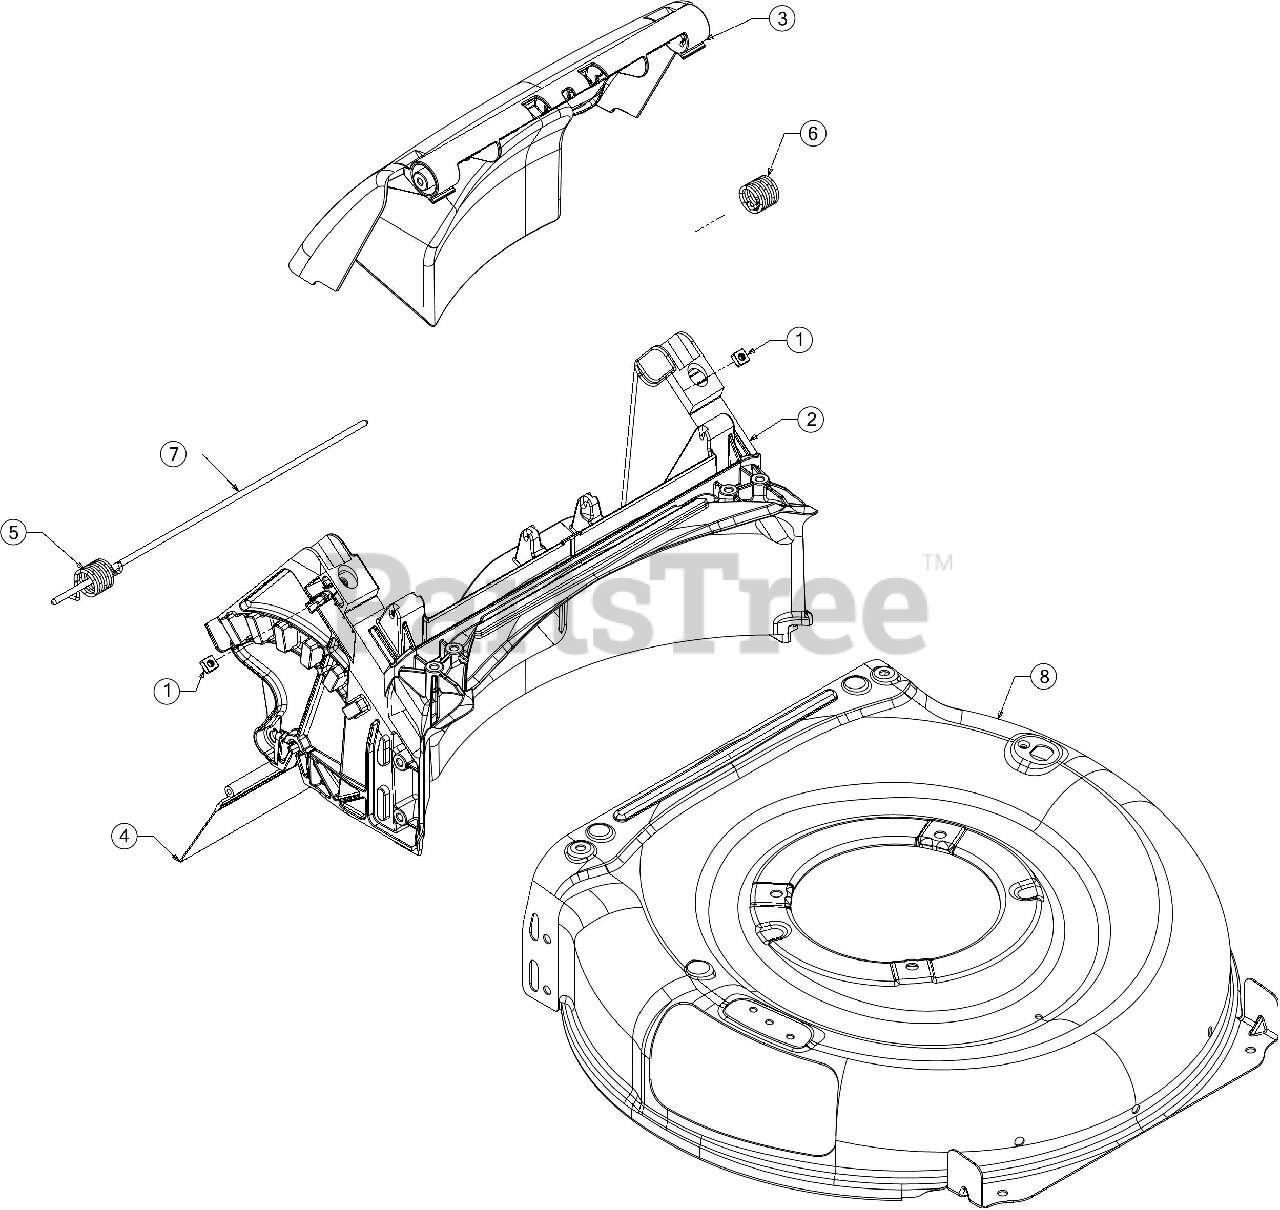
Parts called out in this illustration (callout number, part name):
1	SQUARE NUT 1/4-20
2	DOOR ASSEMBLY
3	REAR DOOR ASSEMBLY
4	TRAILSHIELD
5	TORSION SPRING (RH)
6	TORSION SPRING (LH)
7	REAR DOOR PIVOT ROD
8	21" DECK (3N1)
